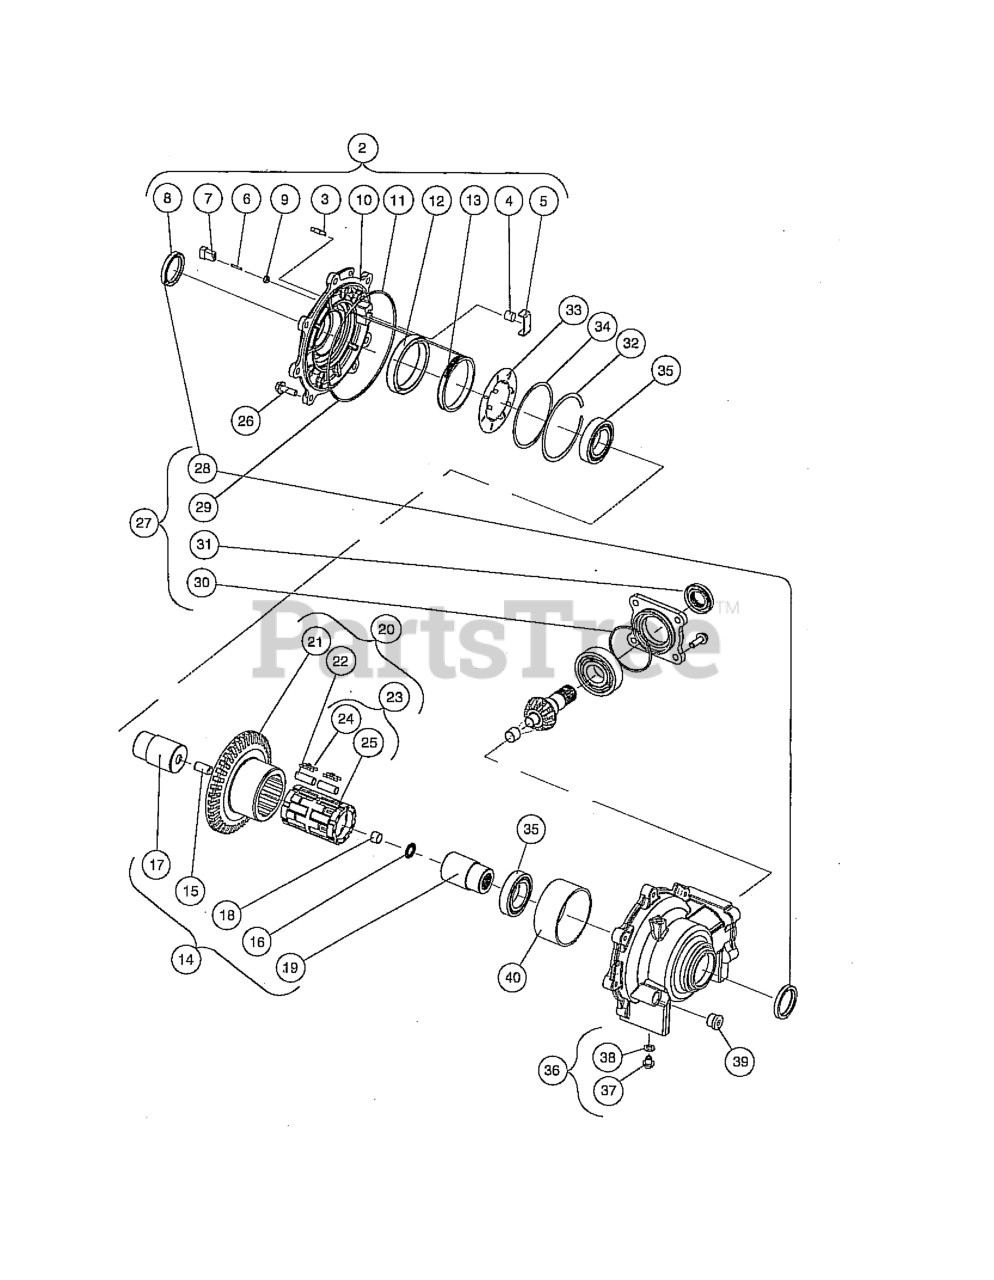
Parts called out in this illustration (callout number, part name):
2	KIT, ASSY, OUTPUT COVER PLATE
3	SET SCREW, #10-24 UNC-3A, PATC
4	THRUST BUTTON
5	THRUST PLATE
14	KIT, ASSY, RACE OUTPUT HUB
15	DOWEL PIN, 1/2" DIA X 1" LG
16	BEARING, NRT, TC815
20	KIT, ASSY, CLUTCH
21	CLUTCH HSG/RING GEAR, MACHINED
23	KIT, ASSY, ROLL CAGE
27	KIT, MINOR REPAIR
32	RETAINING, RING INTERNAL
33	ARMATURE PLATE
34	SHIM, ARMATURE, PLATE
35	BEARING, DGBR, 6008-C3
36	KIT, ASSY, DRAIN PLUG
39	PLUG, OIL FILL
